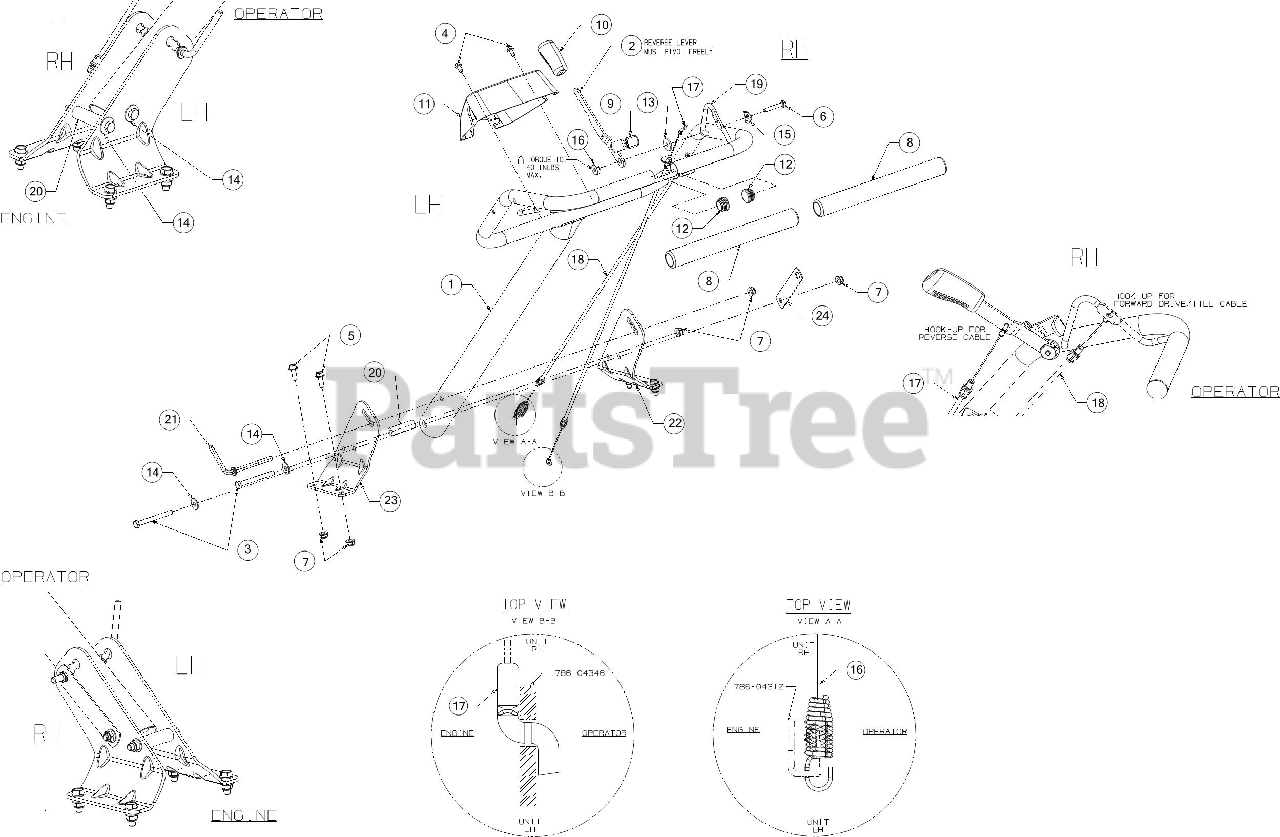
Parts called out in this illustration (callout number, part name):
1	UPPER HANDLE ASSEMBLY
2	REVERSE HANDLE ASSEMBLY
3	HEX SCREW 5/16-18 X 3.00
4	SCREW 1/4-20 X.500
5	SCREW 5/16-18 X .875 GR5
6	BOLT 1/4-20X1.62 GR5
7	FLANGE LOCK NUT 5/16-18
8	FOAM GRIP .970 X 11.0
10	BRAKE HANDLE GRIP
11	HANDLE COVER W/O SWITCH HOLE
13	FLAT WASHER
14	BELL WASHER .337 X.867 X .057
15	SADDLE WASHER
16	SHOULDER SPACER
17	REVERSE CABLE
18	FORWARD CABLE
21	CRANK ADJUST HANDLE
22	HANDLE BRACKET (RH)
23	HANDLE BRACKET (LH)
24	RETURN BRACKET
